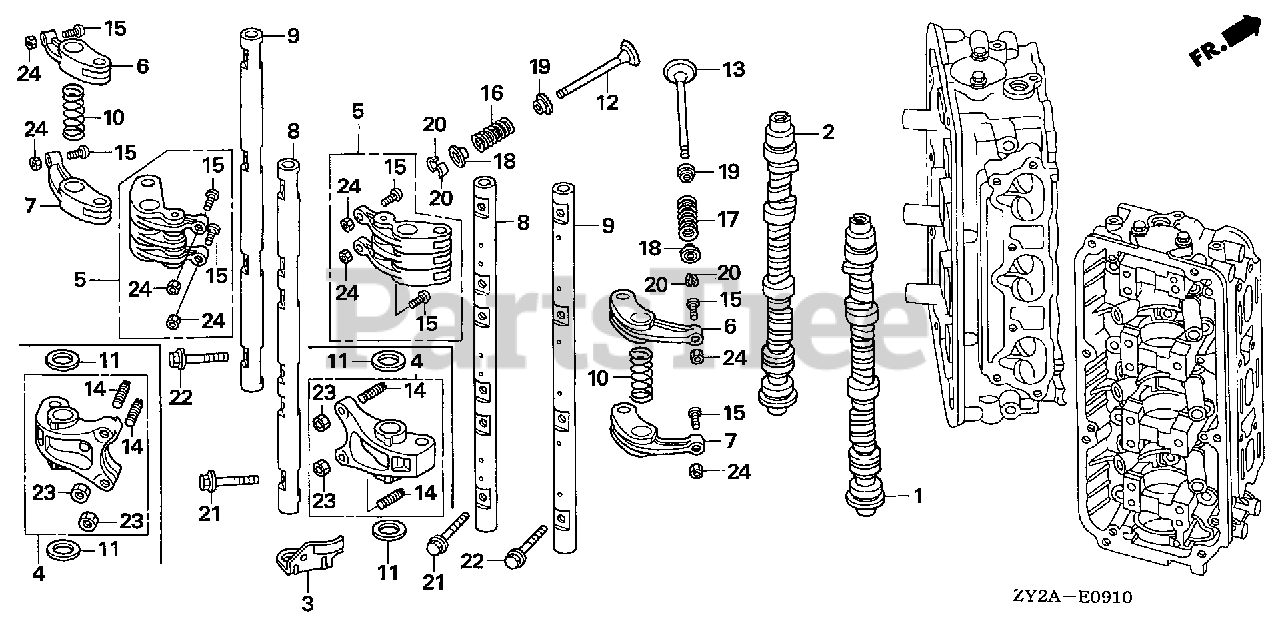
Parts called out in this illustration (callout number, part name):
1	CAMSHAFT, R.
2	CAMSHAFT, L.
3	ARM, FUEL PUMP ROCKER
5	ARM ASSY., IN. ROCKER
6	ARM A, EX. ROCKER
7	ARM B, EX. ROCKER
8	SHAFT, IN. ROCKER ARM
9	SHAFT, EX. ROCKER ARM
10	SPRING, ROCKER ARM
12	VALVE, IN.
13	VALVE, EX.
15	SCREW, TAPPET ADJUSTING
16	SPRING, IN. VALVE (GRAY) (ASSOCIATED SPRING)
17	SPRING, EX. VALVE (YEL/GRN) (ASSOCIATE)
18	RETAINER, VALVE SPRING
19	SEAT, VALVE SPRING
20	COTTER, VALVE (FUJI VALVE)
21	BOLT, FLANGE (8X30)
22	BOLT, FLANGE (8X40)
24	NUT, TAPPET ADJUSTING
